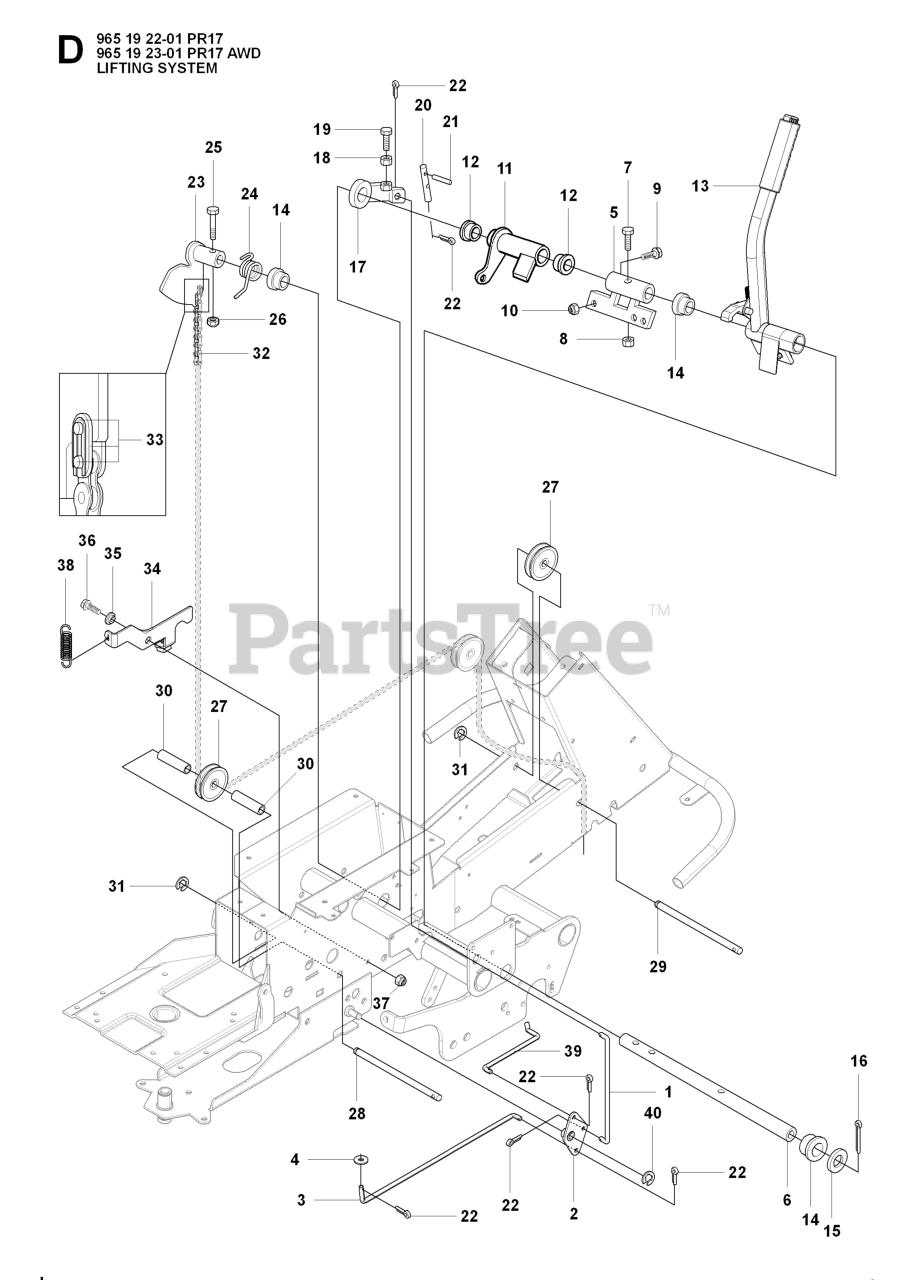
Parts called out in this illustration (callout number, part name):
9	SCREW M6S 8X25
10	NUT
12	BEARING FLANGE
13	LIFTING LEVER ASSY
14	BEARING FLANGE
17	LEVER CLUTCH
18	NUT
20	RP PIN
35	WASHER
36	BOLT
37	LOCKNUT M8
40	RETAINING RING
